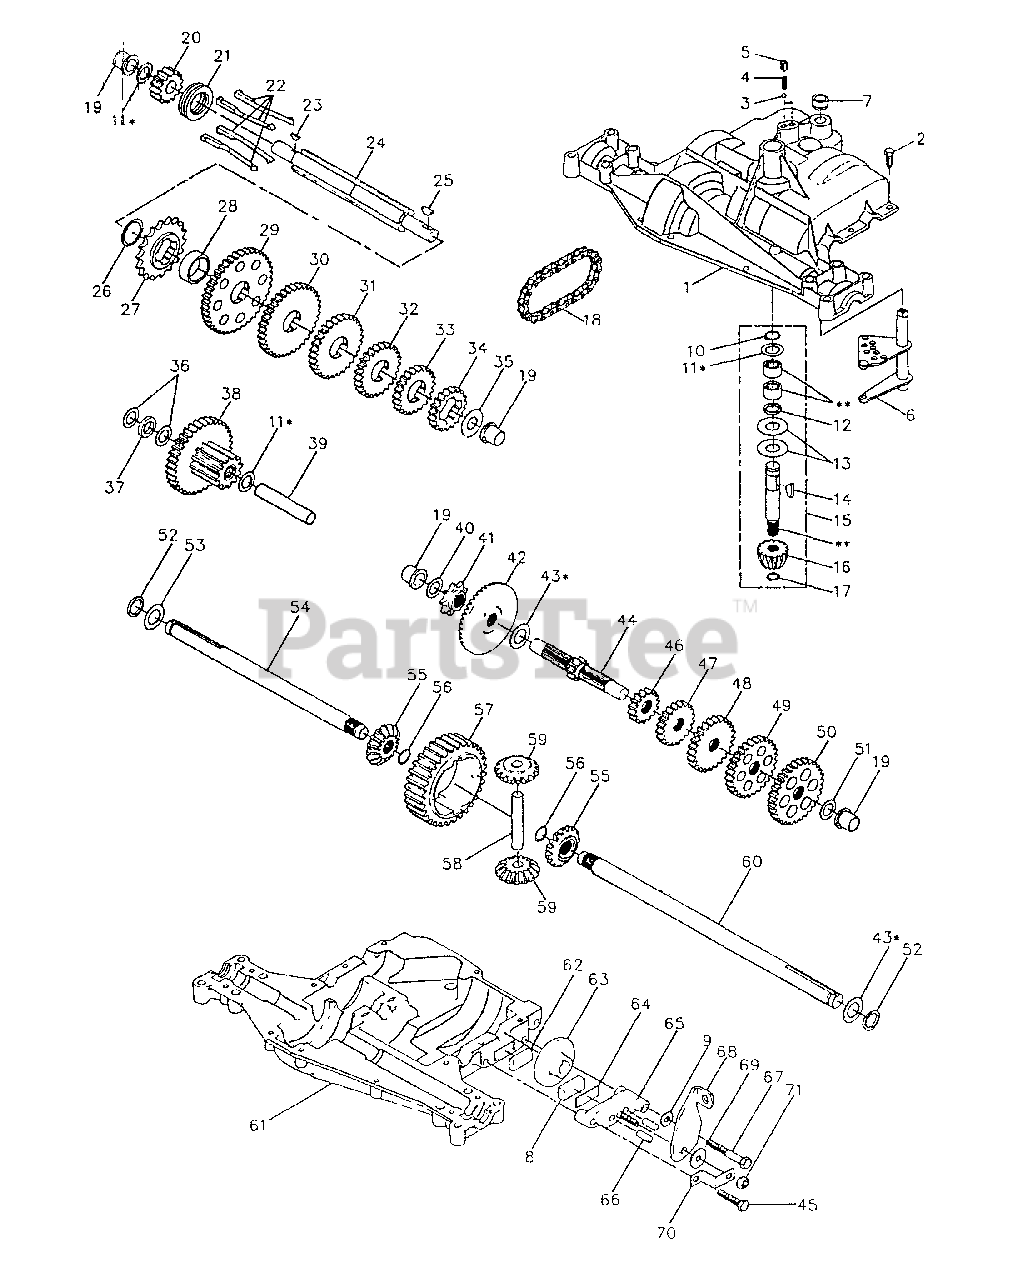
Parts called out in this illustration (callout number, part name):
1	Housing, Upper
2	Screw, Tapping 1/4 - 20 x .734 L
3	Ball, Detent
4	Spring, Detent
5	Screw, Set
6	Assembly, Shifter
8	Puck, Friction
9	Washer, Plain, .325 x .750 x 059
10	Ring, Retaining
11	Washer, Plain, .632 x 1.00 x .010
11	Washer, Plain, .632 x 1.00 x .020
11	Washer, Plain, .632 x 1.00 x .026
11	Washer, Plain, .632 x 1.00 x .031
11	Washer, Plain, .632 x 1.00 x .036
11	Washer, Plain, .632 x 1.00 x .041
11	Washer, Plain, .632 x 1.00 x 046
11	Washer, Plain, .632 x 1.00 x .050
11	Washer, Plain, .632 x 1.00 x .060
11	Washer, Plain, .632 x 1.00 x .082
13	Washer, Plain, .632 x 1.38 x .046
14	Key, Woodruff # 9
15	Assembly, Kit, Input Shaft
16	Pinion, Bevel, 14 T
17	Ring, Retaining
18	Chain, 24 Pitches
19	Bearing, Flange
20	Gear, Spur, 14T
21	Collar, Clutch
22	Key, Clutch
23	Key, Woodruff # 3
24	Shaft, Intermediate
25	Key, Woodruff # 61
26	Ring, Retaining
27	Sprocket, 18 T
29	Gear, Spur, 40 T
30	Gear, Spur, 35 T
31	Gear, Spur, 30 T
32	Gear, Spur, 25 T
33	Gear, Spur, 22 T
34	Gear, Spur, 19 T
35	Washer, Plain, .640 x 1.37 x .061
36	Washer, Plain, .632 x 1.00 x .026
37	Spacer, .630 x 1.00 x .169
38	Assy., Gear, Comb., 12 T & 35 T
39	Shaft, Idler
40	Washer, Plain, .631 x 1.00 x .015
41	Sprocket, 9 T
42	Gear, Bevel, 42 T
43	Washer, Plain, .758 x 1.12 x .010
43	Washer, Plain, .758 x 1.12 x .015
43	Washer, Plain, .758 x 1.12 x .020
43	Washer, Plain, .758 x 1.12 x .025
43	Washer, Plain, .758 x 1.25 x .020
43	Washer, Plain, .758 x 1.25 x .025
43	Washer, Plain, .758 x 1.25 x .031
43	Washer, Plain, .758 x 1.25 x .035
43	Washer, Plain, .758 x 1 25 x .040
43	Washer, Plain, .758 x 1.25 x .045
43	Washer, Plain, .758 x 1 25 x .050
44	Shaft, Drive
45	Screw, Tapping, 5/16 x 18 x 1.44 Lg.
46	Gear, Spur, 15 T
47	Gear, Spur, 20 T
48	Gear, Spur, 25 T
49	Gear, Spur, 28 T
50	Gear, Spur, 31 T
51	Washer, Plain, .632 x 1 00 x .060
52	Seal, Felt
53	Washer, Plain, .758 x 1.25 x .062
54	Axle, L.H.
55	Gear, Miter, 15 T
56	Ring, Retaining
57	Gear, Spur, 32 T
58	Shaft, Cross
59	Gear, Miter, 15 T
60	Axle, R.H.
61	Housing, Lower Friction
62	Puck, Friction
63	Disc, Brake
65	Jaw, Brake
66	Pig, Jowel
67	Screw, Tapping, 5/16 - 18 x 2.25
68	Lever, Actuating
69	Washer, Plain, .321 x 1.00 x .055
70	Bracket, Anti-Rotation
71	Nut, Lock 5/16 - 24
